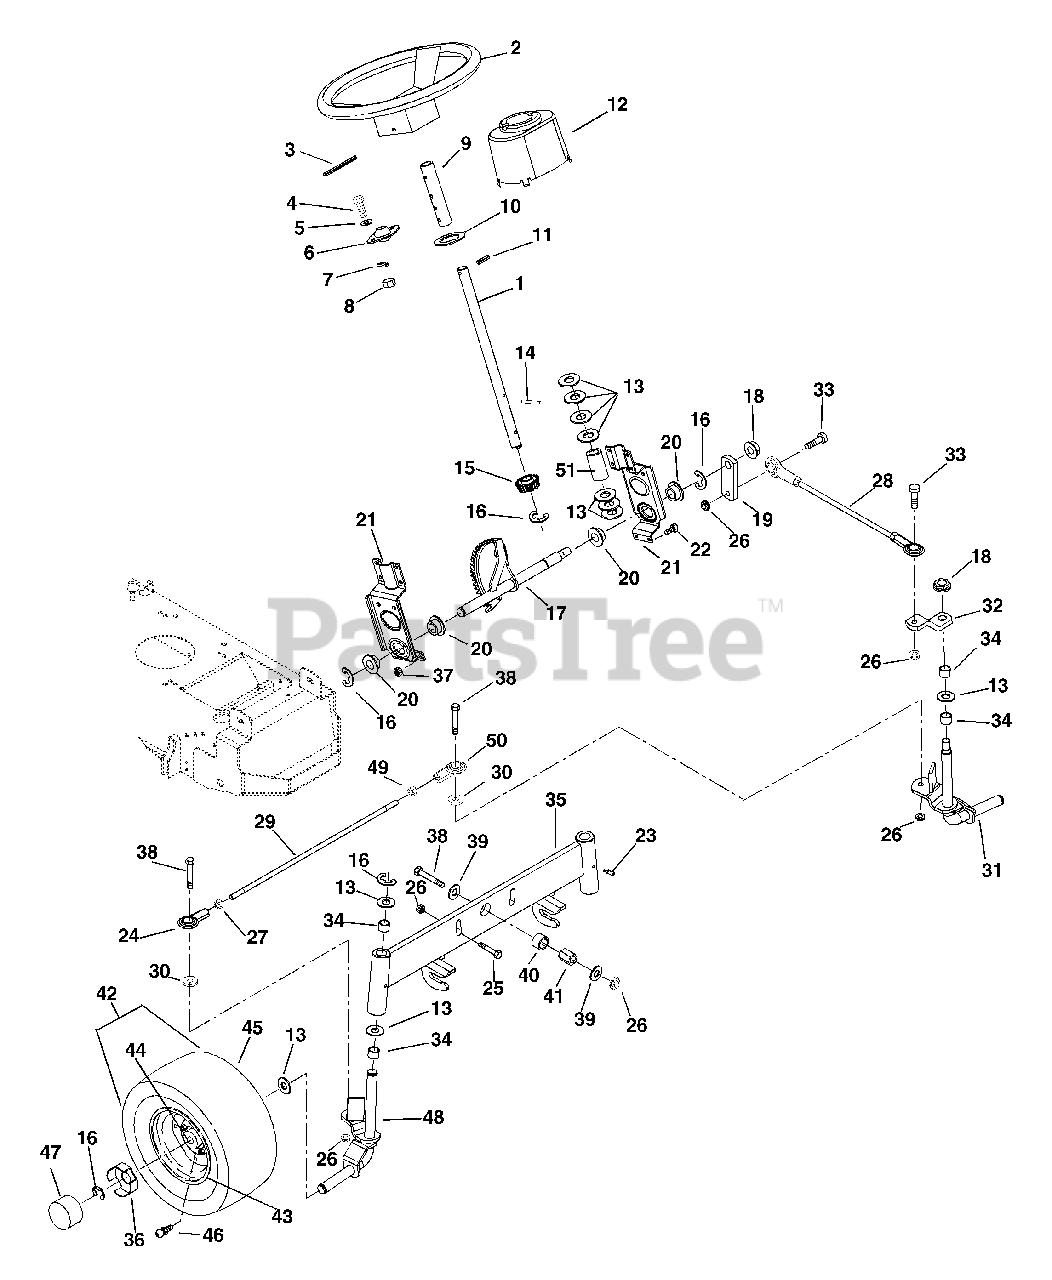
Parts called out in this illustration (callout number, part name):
1	COLUMN, STEERING
2	STEERING WHEEL
3	PIN-ROLL .250X1.75
4	@BLT-HEX .31-18X.75 GR5 YWZC
5	@WSHR-FL-STL.312X.734X.065 YWZ
6	BRG-FLG .751X2 HOLESX.81
7	WSHR-LK .312X.097 HVY YWZC
8	@NUT-HEX .31-18 YWZC
9	TUBE .754 X .999 X 5.00
10	WSHR-FL-STL.754X1.125X.062YWZC
11	PIN-ROLL .250X1.000
12	CONE- STEERING COLUMN
13	WSHR-FL-STL.755X1.375X.062YWZC
14	PIN .249X1.125 DRIV-LOK SP
15	PINION GEAR-STEERING
16	RG-RTNG-EXT .750X.050
17	GEAR, STEERING
18	NUT-LK .563-18 GR5 YWZC
19	ARM, STEERING ROD
20	BSHG-FLG .750X1.093X.625X1.375
21	BRACKET-STEERING GEAR
22	@BLT-HEX .25-20X.75 GR5 YWZC
23	FTG-LUBE .25-28X.256 YWZC
24	ROD END, .38 RH
25	@BLT-HEX .38-16X1.25 GR5 YWZC
26	@NUT-LK-CTR .38-16 YWZC
27	NUT-JAM .375-24 YWZC
28	LINK, DRAG
29	ROD, TIE
30	BSHG-SLV .377X.624X.370
31	SPINDLE - LH
32	ARM, STEERING SPINDLE
33	BLT-BTHD .38-16X1.25 GR5
34	BSHG-SLV .750X.814X .750 BRZ
35	AXLE, FRONT
36	SPINDLE CUP
37	@NUT-LK-CTR .25-20 YWZC
38	@BLT-HEX .38-16X1.75 GR5 YWZC
39	WSHR-FL-STL .380X1.50X.125YWZC
40	BSHG-SLV .626X1.000X.524 HEX
41	BSHG-SLV .377X.623X.775 HEX
42	T/WHL ASSY 15X6.00-6
43	RIM
44	BSHG .75 BORE
46	FTG- LUBE .25-28X.97
47	HUB CAP
48	SPINDLE - RH
49	NUT-JAM .375-24 LH YWZC
50	END, ROD-.38 LH
51	BSHG-SLV .753 X 2.00 SELF LUB.
